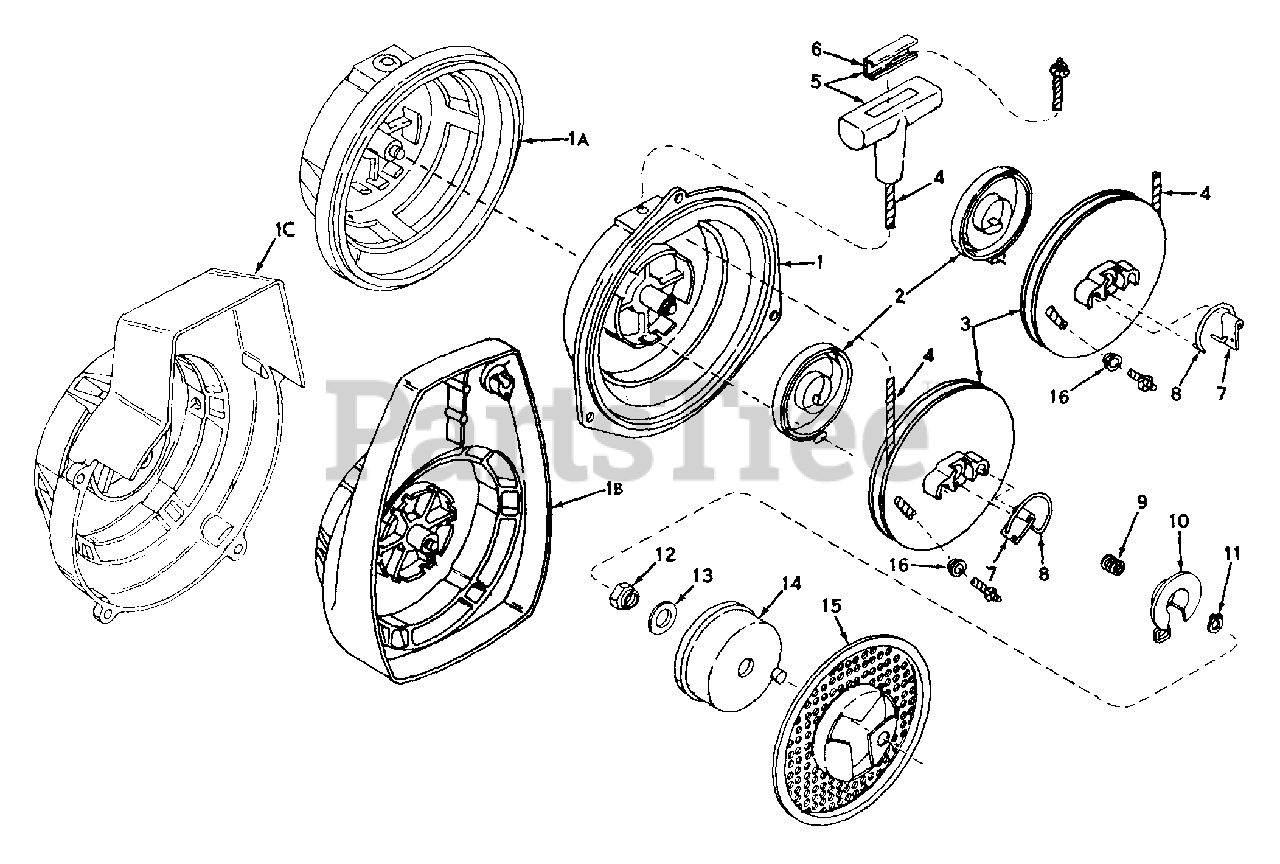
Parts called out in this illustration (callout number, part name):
1B	Housing Assy., Shroud & Starter
2	Spring, Rewind
3	Pulley, Starter rope
4	Rope, Starter (Length 49")
5	Handle Assy., Starter rope (Incl. 6)
6	Insert, Handle
7	Dog, Starter
8	Spring, Starter dog
9	Spring, Brake
11	"E" Ring, Truarc
16	Grommet
